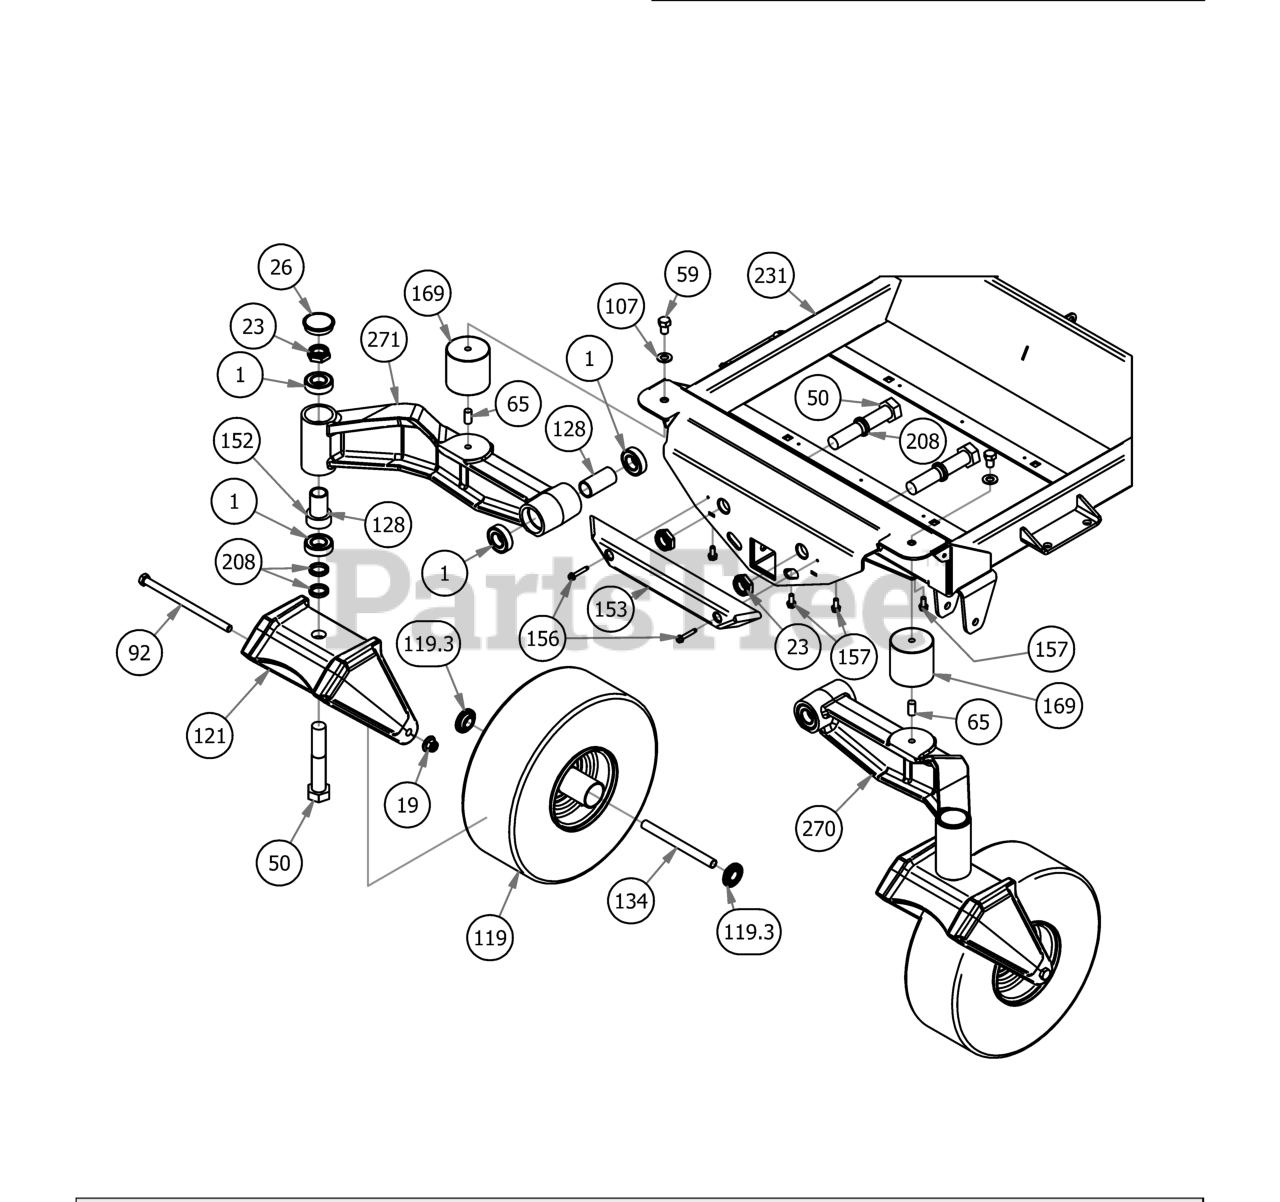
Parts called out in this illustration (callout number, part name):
1	1641 BEARING W/2 CONTACT RUBBER SEALS
19	1/2-13 NYLON INSERT FLANGE LOCKNUT ZINC
23	1" Fine Thread 1/2 Nylock Nut
26	2017 Bearing Cover
50	1-14 x 5.5 Hex Bolt Grade 8 Zinc Yellow
59	1/2" x 3/4" Hex Bolt
65	1/2-13 x 1" Stud
92	1/2" x 9" GR 5 Hex Bolt
107	1/2" Washer (Grade 8)
119	2019 15x6.00-6 Non Pneumatic Black Front Assembly
119.3	1-3/4" Bearing-Large Bore Front Rim
121	2019 Rebel, Rogue, Renegade Front Fork
128	2016 Front Bearing Spacer
134	Front Wheel Spanner
152	Rubber Stabilizer (Front Forks) [R series]
153	2017 XP Bumper
156	1/4" x 1 1/2" Self Tapping Screw
157	5/16 x 3/4 washer head type F screw
169	Vibration Mount-Blue Dot
208	Spacer, 1x1.375x.25
231	2019 Horizontal Diesel Frame
270	2019 Front I-Beam Left
271	2019 Front I-Beam Right
